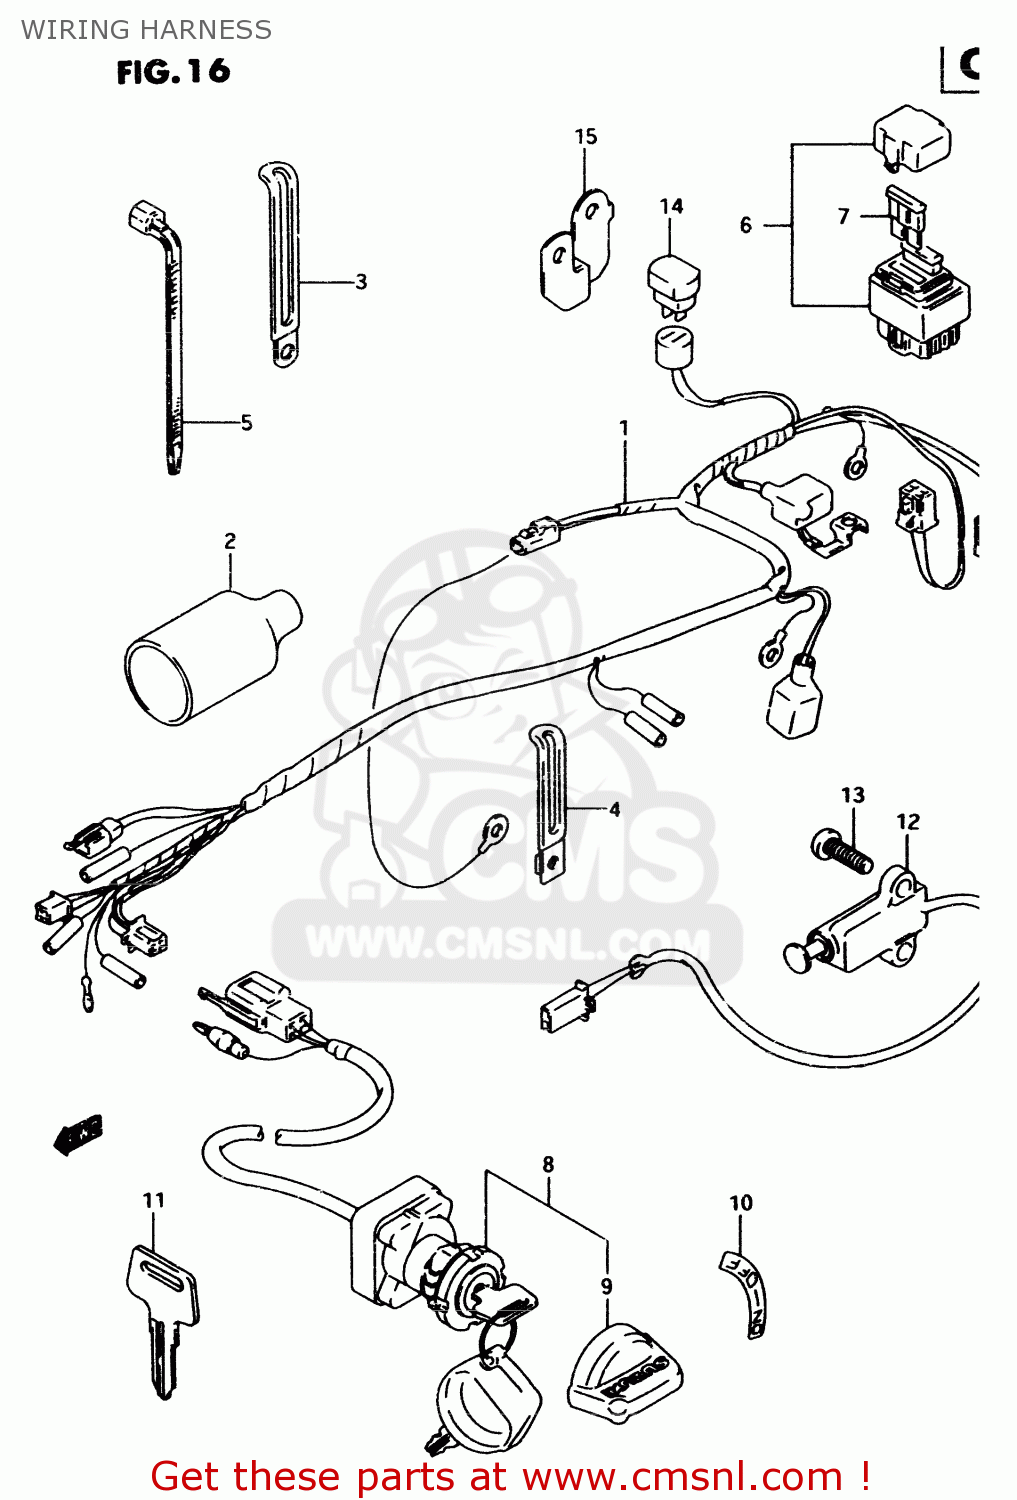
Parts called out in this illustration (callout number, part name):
1	HARNESS,WIRING
2	BOOT,WIRING HARNESS
3	CLAMP(L:80)
4	CLAMP(L:80)
5	CLAMP L:165
6	BOX ASSY,FUSE
7	FUSE(5A)
8	SWITCH ASSY,IGNITION
9	MASCOT,KEY
10	PLATE,CONTROL INDENTIFICATION
11	KEY,BLANK(TYPE:C)
12	SWITCH ASSY, PARKING BRAKE
13	SCREW, 6X20
14	BREAKER ASSY,CIRCUT
15	BRACKET,CIRCUIT BREAKER
